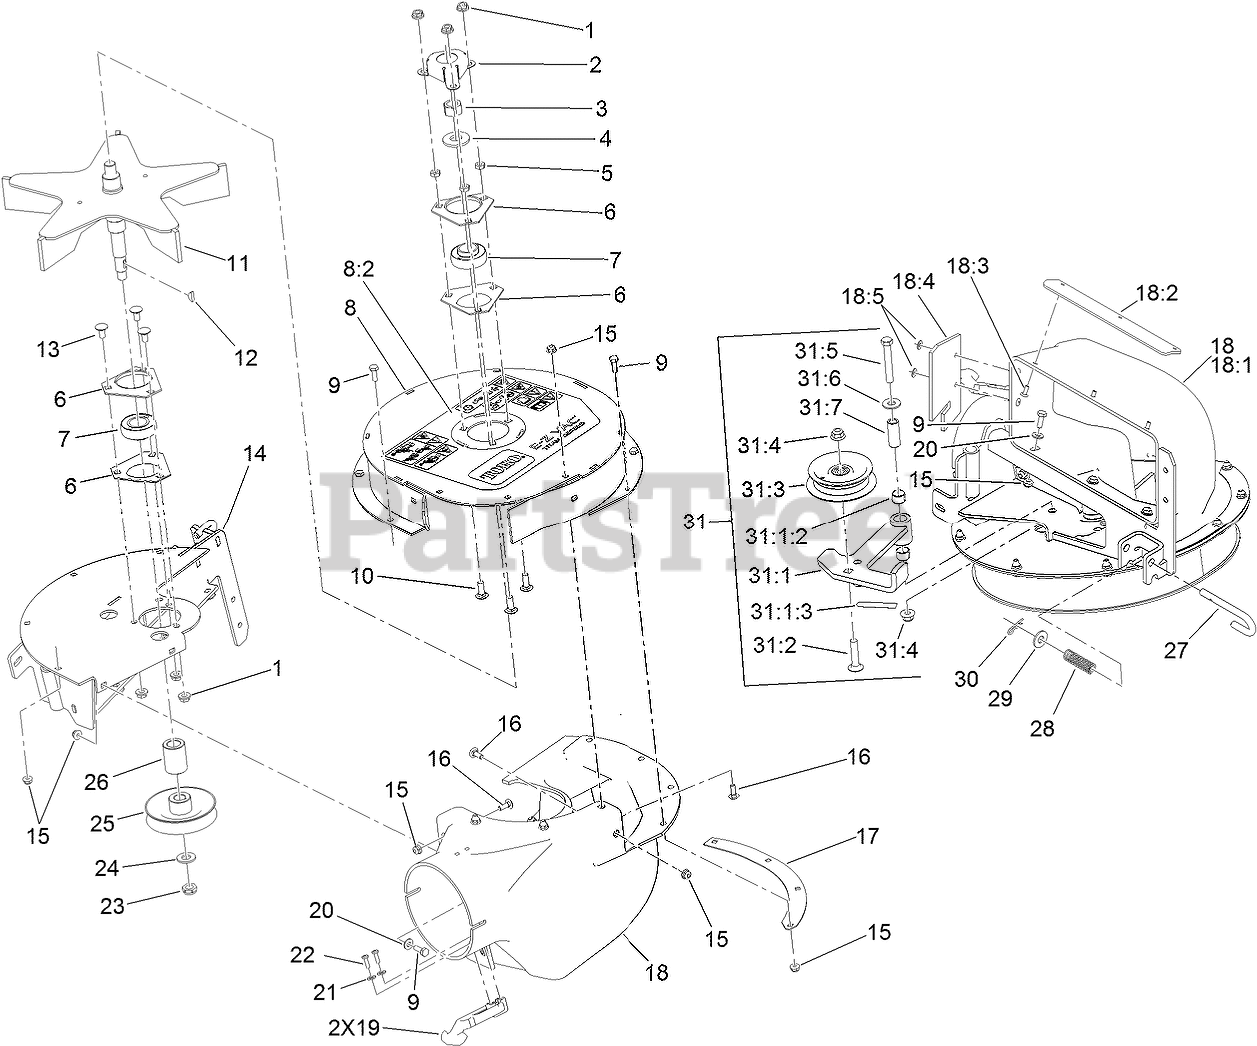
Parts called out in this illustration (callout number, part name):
1	NUT-HF
2	COVER-NUT
3	NUT-HEX
4	WASHER-SPRING
5	NUT-JAM
6	HOUSING-FLANGE
7	BEARING
8	UPPER HOUSING ASM
8:2	DECAL-WARNING
9	SCREW-HH
10	BOLT-CARR
11	IMPELLER
12	KEY-WOODRUFF
13	SCREW-CARR
14	FRAME-BLOWER
15	NUT-HF
16	BOLT-CARR
17	PLATE-BACKING
18	BLOWER CHUTE ASM
18:1	CHUTE-BLOWER, SMALL
18:2	PLATE-STIFFENER
18:3	RIVET-BLIND
18:4	BAFFLE-HOUSING
18:5	WASHER-FLAT
19	LATCH-RUBBER
20	WASHER-FLAT
21	WASHER-FLAT
22	SCREW-PPH
23	NUT-LOCK, NI
24	WASHER-FLAT
25	PULLEY
26	SPACER
27	PIN-LATCH
28	SPRING-COMPRESSION
29	WASHER-FLAT
30	PIN-COTTER
31	IDLER ARM ASM
31:1	IDLER ARM WITH BUSHING ASM
31:1:2	BUSHING
31:1:3	DECAL-WARNING
31:2	SCREW-CARR
31:3	IDLER-FLAT
31:4	NUT-HF, NI
31:5	SCREW-HH
31:6	WASHER-FLAT
31:7	BUSHING
